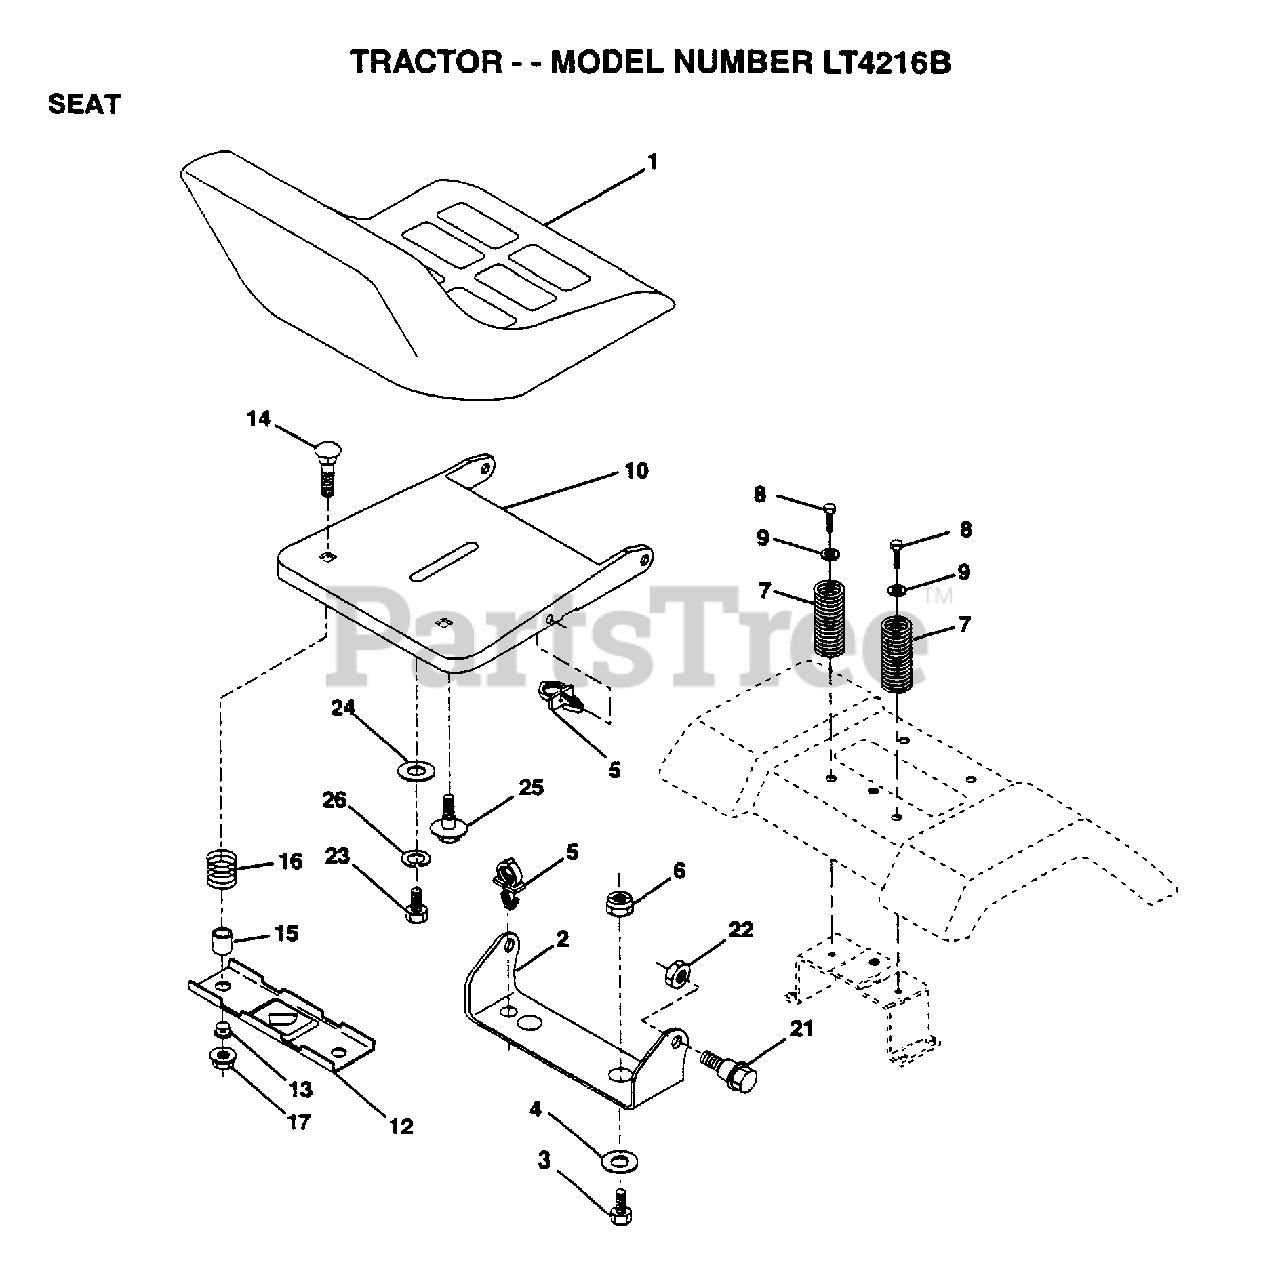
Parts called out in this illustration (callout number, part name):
2	BRACKET PVT SEAT
3	BOLT
4	WASHER PM
5	CLIP.PUSH-IN.HING
6	NUT
7	SPRING COMPRESSIO
8	SCREW GTV
9	WASHER
12	BRKT SWITCH
13	BUSHING
15	SPLIT SPACER
16	SPRING
21	BOLT.SHLD.5/16-18
22	NUT
23	BOLT
24	WASHER
25	"BOLT,SHOULDER"
26	LOCKWASHER
